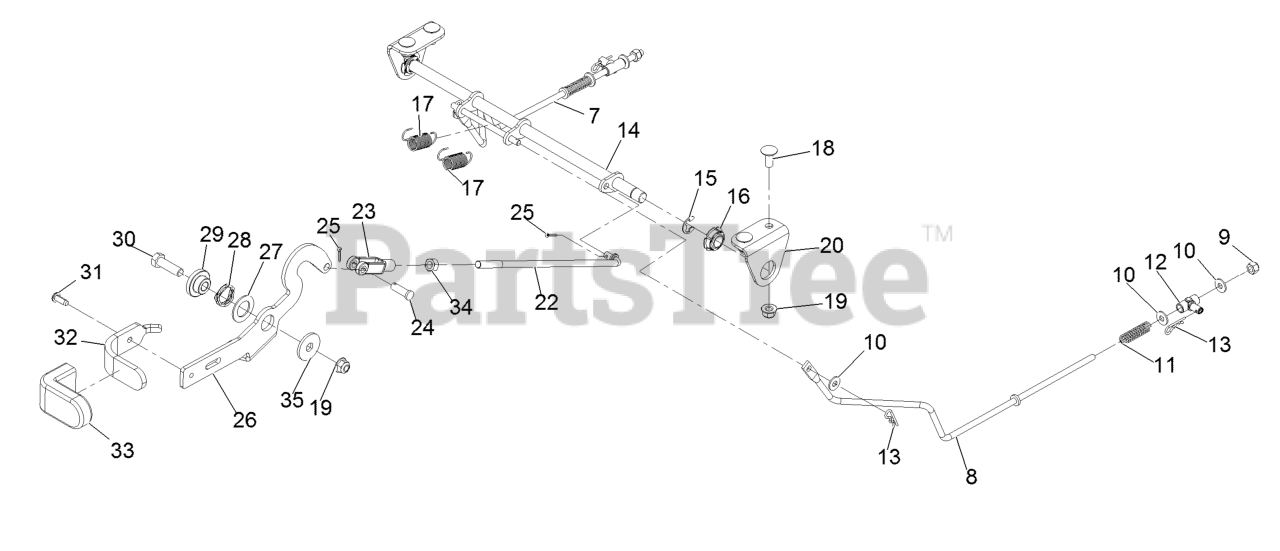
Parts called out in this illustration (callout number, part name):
7	ROD-BRAKE, RH
8	ROD-BRAKE, LH
9	NUT-LOCK, NI
11	SPRING-COMPRESSION
12	MOUNT-PIVOT
14	PIVOT-BRAKE
15	RING-RETAINING, EXTERNAL
16	BEARING-SPHERICAL
17	SPRING-EXTENSION
18	SCREW-CARR
19	NUT-HF, NI
20	ANGLE-MOUNT PIVOT
22	ROD-LINK HANDLE
23	YOKE-ADJUSTABLE
24	PIN-CLEVIS
25	PIN-COTTER
26	LEVER-BRAKE
27	WASHER-THRUST
28	WASHER-WAVE
29	PIVOT-FLANGE
30	SCREW-HH
32	HANDLE-BRAKE
33	GRIP-LEVER
34	NUT-HEX
35	WASHER
